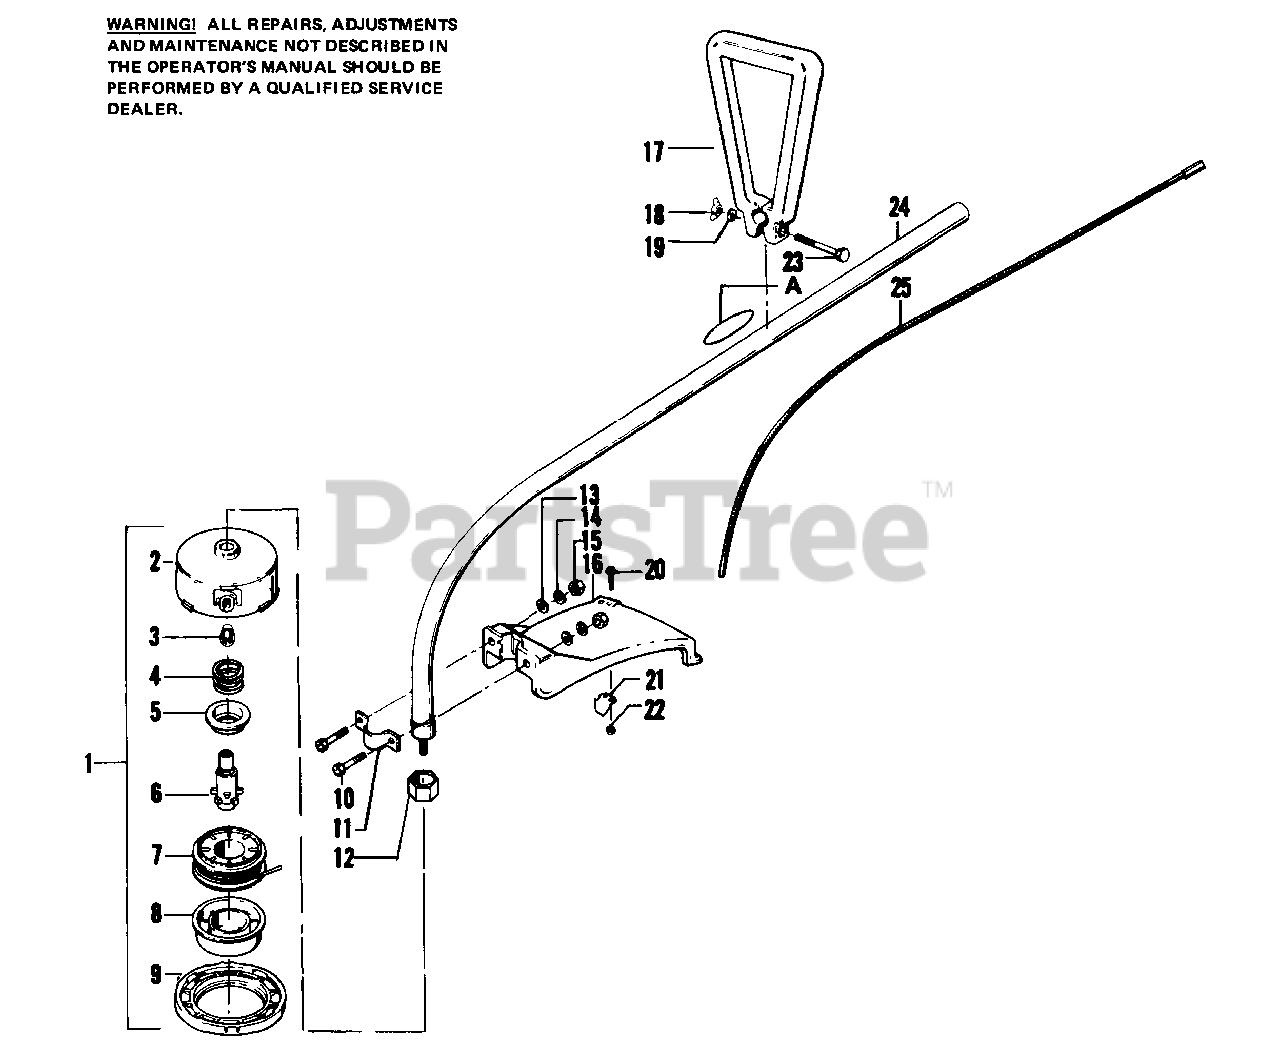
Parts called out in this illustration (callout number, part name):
1	Cutting Head Ass'y (Inc. # 2 - 9)
2	Hub w/ Line Saver
3	Line Saver
4	Spring
5	Adaptor - Spring
6	Drive Gear
7	Spool w/Line
8	Release Button
10	Bolt - Shield
11	Bracket - Shield (1/4-20 x 1-3/4)
12	Dust Cup
13	Washer - Flat
14	Washer - Lock 1/4
15	Nut - Shield 1/4-20
17	Assist Handle
18	Wing Nut - 1/4-20
19	Washer - 1/4 Flat
20	Screw - Line Limiter (10-24x1)
21	Limiter - Line
22	Nut - Line Limiter
23	Hex Bolt - 1/4-20 x 2-1/4
24	Drive Shaft Ass'y (Inc. # 12)
25	Flexible Shaft Ass'y
A	Decal - Attachment Warning
